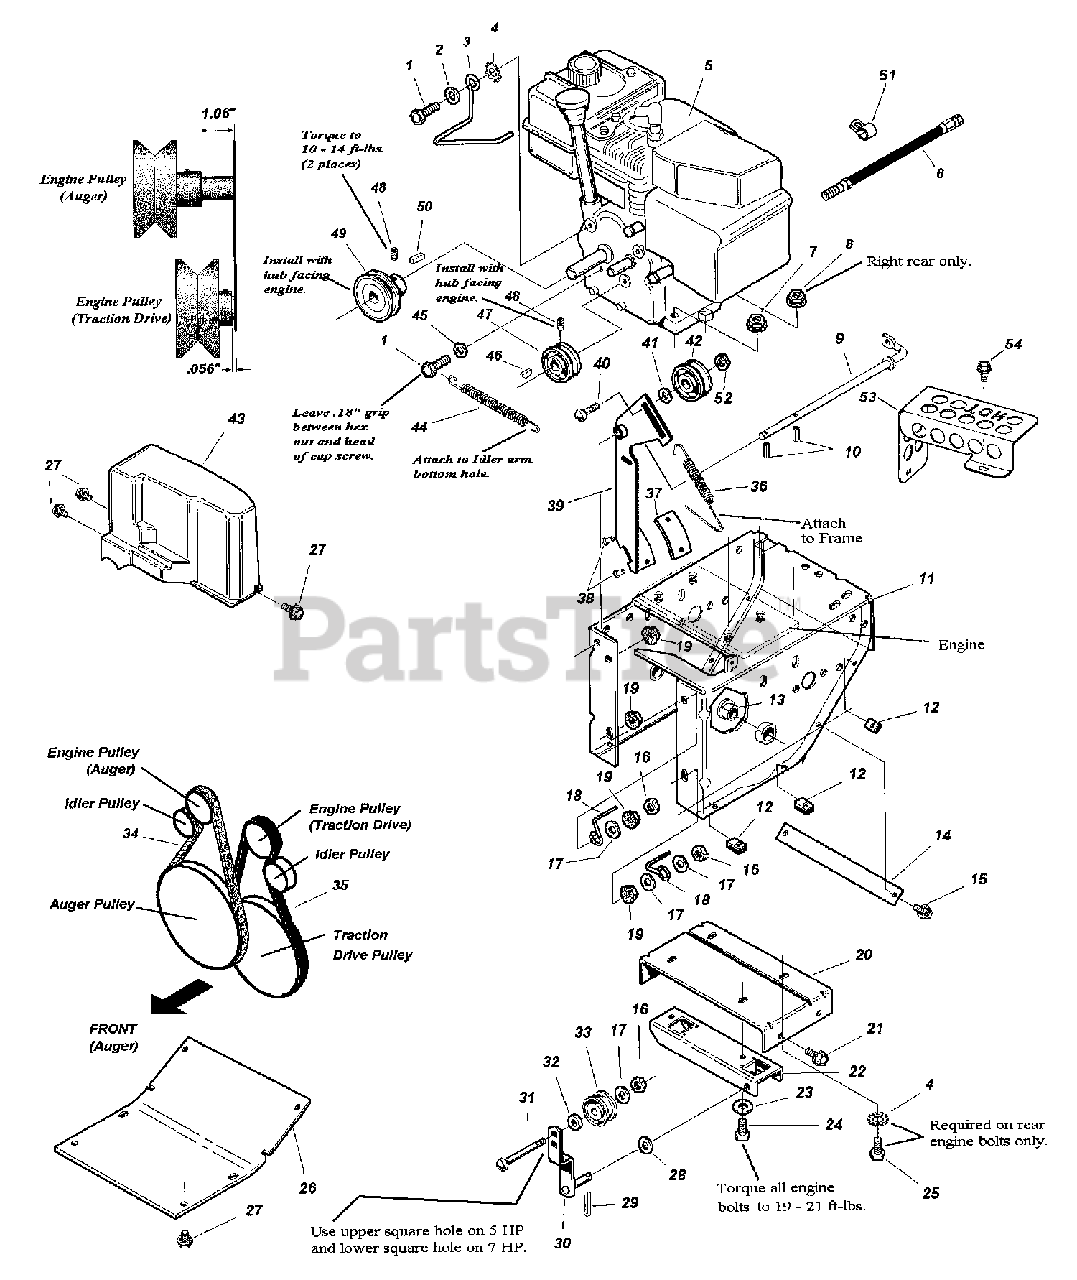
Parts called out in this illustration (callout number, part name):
1	SCREW, 5/16-24 x 3/4" Hex Head Cap, GR 5
2	WASHER, 5/16" Flat
3	WIRE, Belt Stop
4	LOCKWASHER, 5/16" Exterior Tooth
5	* ENGINE, 5HP Tecumseh
6	HOSE, Oil Drain
7	NUT, 5/16-18 Hex Flange Lock- small
8	NUT, 5/16-18 Hex Flange Lock
9	ROD, Idler
10	ROLL PIN, 3/16 x 3/4"
11	WELDMENT, Intermediate Frame- Red
12	SPEED NUT, 1/4-20 U-Type
13	BUSHING, 1.00 long
14	SUPPORT, Tie Bar
15	SCREW, #10-24 x 1/2" Hex Washer Self-Tap
16	JAM NUT, 3/8-16 Hex Center Lock
17	WASHER, 3/8" Flat
18	ROD, Belt Guide
19	NUT, 3/8-16 Hex Nyloc Heavy Thin
20	SUPPORT, Frame
21	SCREW, 5/16-18 x 1/2" Hex Washer Self-Tap
22	SUPPORT, Pivot
23	WASHER, 5/16" Flat
24	SCREW, 5/16-18 x 1-3/4 Hex Head Cap, GR 5
25	SCREW, 5/16-18 x 1-3/4 Hex Head Cap, GR 5
26	COVER, Bottom- Red
27	SCREW, 1/4-20 x 5/8" Hex Washer Self-Tap
28	WASHER, 7/16" Flat
29	COTTER PIN, 1/8 x 3/4"
30	WELDMENT, Idler Arm
31	BOLT, 3/8-16 x 1-1/4" Short Square Neck Carriage
32	SPACER, .377 ID x .75 OD x .312 Long
33	PULLEY, Idler
34	BELT, V Groove, 4L Section; 36.00" nom. effective length
35	BELT, V Groove, 3L Section; 35.25" effective length
36	SPRING, Extension
37	PAD, Brake
38	RIVET, Blind
39	ASSEMBLY, Idler Arm w/Brake Pad
40	BOLT, 3/8-16 x 1-3/4 Short Square Neck Carriage, GR 5
41	WASHER, 3/8" Flat (.41 ID x 1.00 OD x .13 Thick)
42	PULLEY, Idler
43	COVER, Belt
44	SPRING, Idler- Extension
45	JAM NUT, 5/16-24 Hex
46	KEY - Hi Pro .125 x .625 HP 504 SAE1035
47	PULLEY, V Groove
48	SET SCREW, 5/16-18 x 5/16" Hex Recess, Cup Point
49	PULLEY, 2.75 OD
50	KEY, 3/16x3/16x1"
51	HARNESS CLIP
52	NUT, 3/8-16 Hex Flange Lock Two Way
53	MUFFLER GUARD, Domestic (Tecumseh)
54	SCREW, #10-24 x 5/8" Hex Washer Self-Tap
